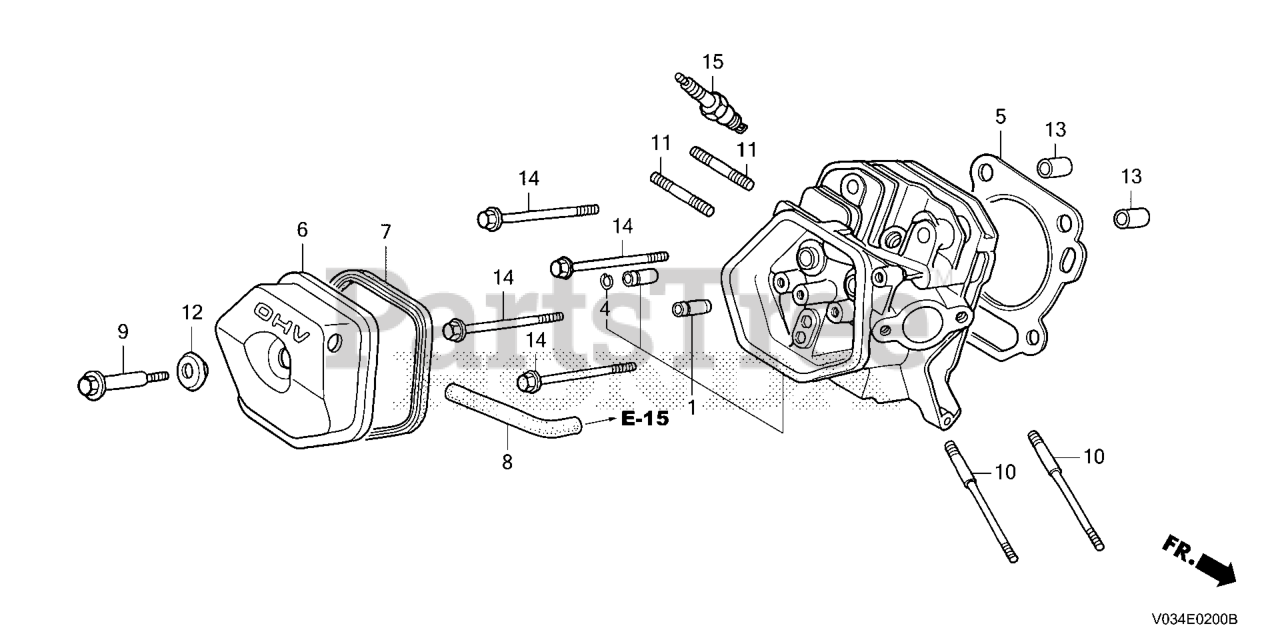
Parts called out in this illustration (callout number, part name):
1	CYLINDER HEAD
2	GUIDE, VALVE (OS)
4	CLIP, VALVE GUIDE
5	GASKET, CYLINDER HEAD
6	COVER, HEAD
7	GASKET, CYLINDER HEAD COVER
8	TUBE, BREATHER
9	BOLT, HEAD COVER
10	BOLT, STUD (8X131.5)
11	BOLT, STUD
11	BOLT 2, STUD (8X32)
12	WASHER, HEAD COVER
13	PIN A, DOWEL (12X20)
14	BOLT, FLANGE (10X80)
15	SPARK PLUG (BPR5ES) (NGK)
15	SPARK PLUG (W16EPR-U) (DENSO)
